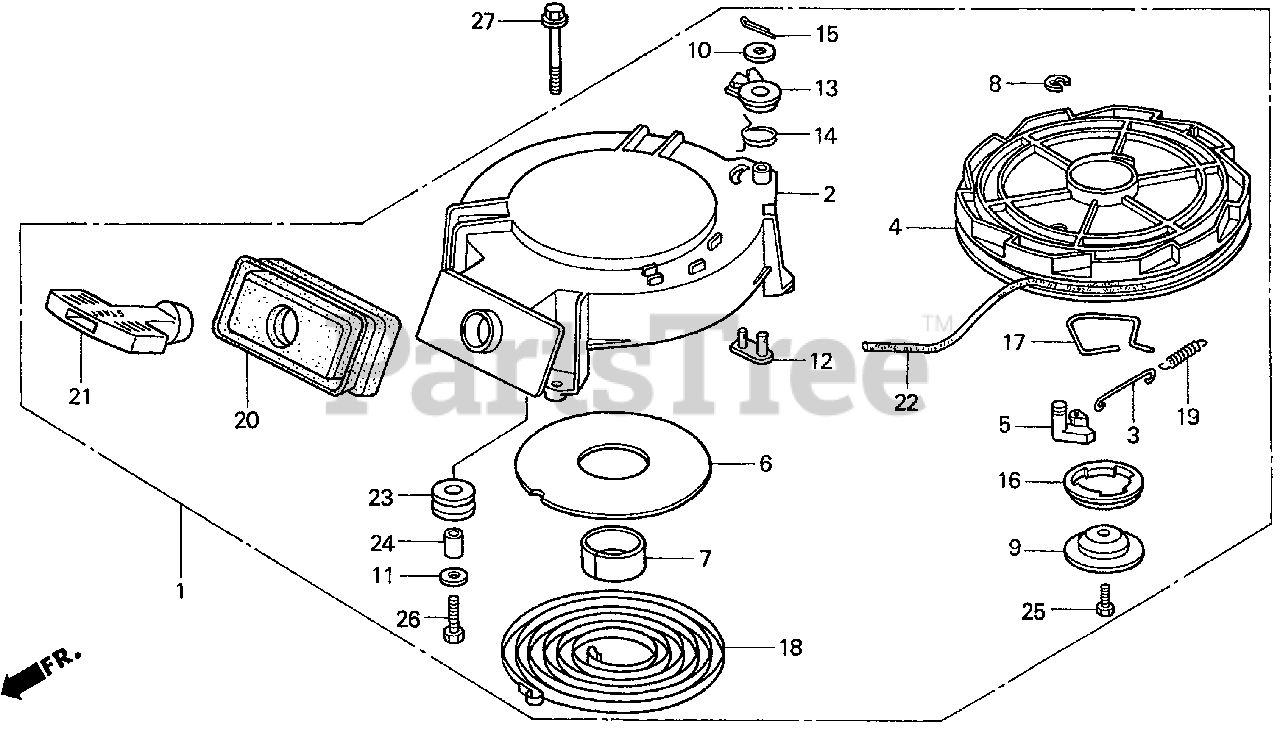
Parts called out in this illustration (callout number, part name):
1	STARTER ASSY., RECOIL
2	CASE, RECOIL STARTER
3	GUIDE, RECOIL STARTER
4	PULLEY, RECOIL STARTER
5	RATCHET, STARTER
9	PLATE, FRICTION
11	WASHER, THRUST
12	STOPPER, REEL
13	ARM, STOPPER
14	SPRING, STOPPER
15	PIN, SPLIT
17	SPRING, FRICTION
18	SPRING, RECOIL STARTER
19	SPRING, RETURN
20	SEAL, RECOIL
21	KNOB, STARTER
22	ROPE, RECOIL STARTER (#6X64") (NA USE ALT:08560-ZG921-11)
23	ROLLER, STARTER
24	GUIDE, ROLLER
25	BOLT (6X20)
26	BOLT, HEX. (6X14)
27	BOLT, FLANGE (6X22)
